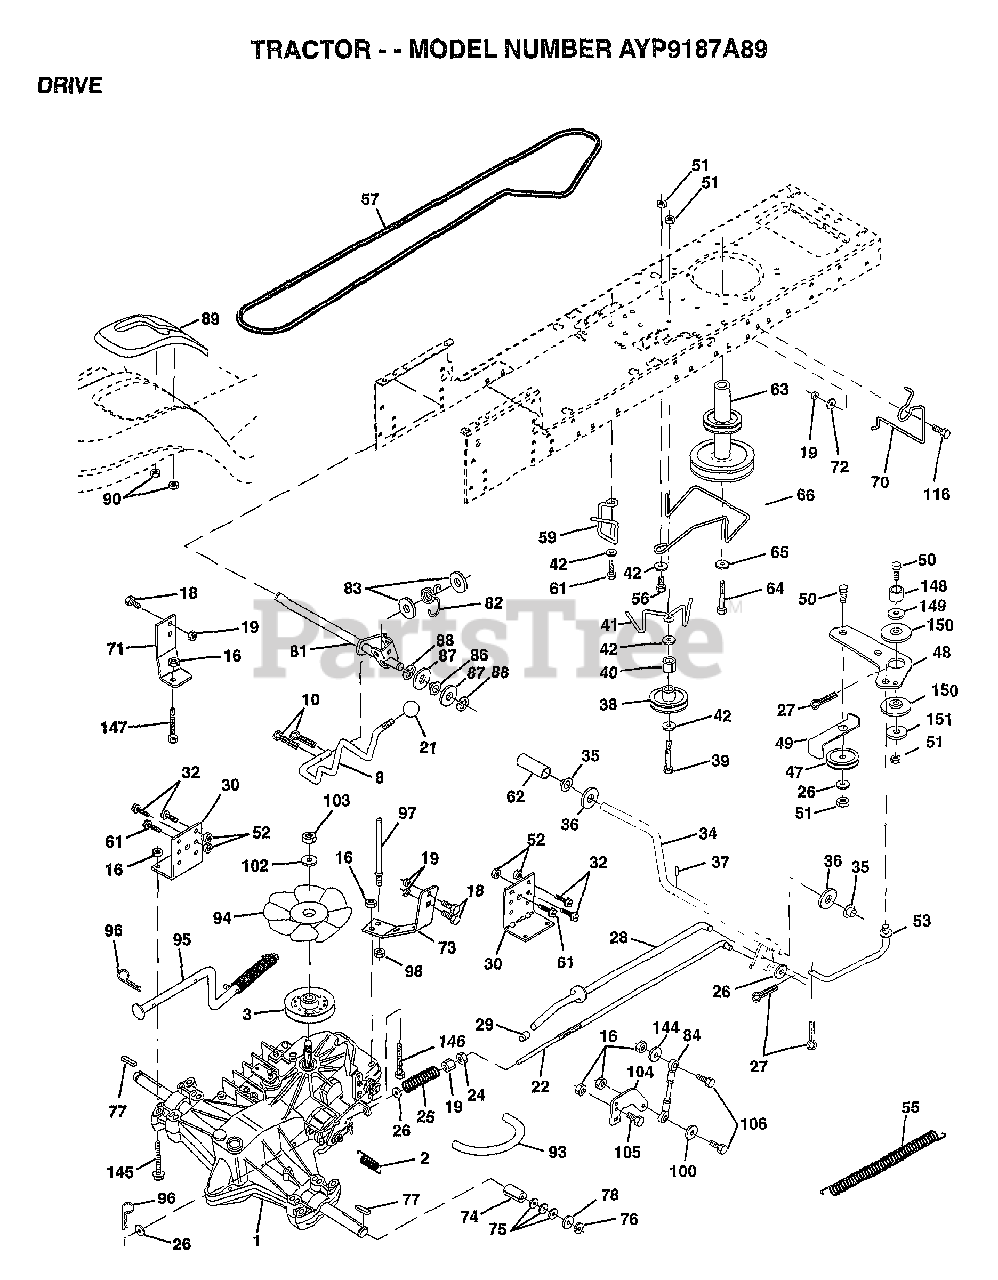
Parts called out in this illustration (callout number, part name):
1	TRANSAXLE.3100650
2	SPRING RET BRAKE
3	PULLEY.TRANSAXLE
8	"ROD SHIFT,FENDER"
10	PIN COTTER 1/8
16	NUT
18	BOLT
19	NUT
21	KNOB T (1/2-HOLE)
22	ROD.BRAKE.HYDRO.
24	NUT
25	SPRING ROD LT
26	WASHER
27	COTTER PIN
28	ROD.BRAKE.PARK.LT
30	TRANSAXLE MTG BKT
32	BOLT
34	SHAFT ASM-PEDAL F
35	NYLON BEARING
36	WASHER LT
38	PULLEY.IDLER.FLAT
39	BOLT
40	SPACER T
42	WASHER
48	BELLCRANK.CLUTCH
49	RETAIN BELT
53	"LINK, CLUTCH T"
55	"SPRING, RETURN LT"
57	V-BELT.GROUND.HYD
59	KEEPER BELT CNTSP
61	SCREW
62	PEDAL COVER T
63	PULLEY.ENGINE
64	BOLT
65	LOCKWASHER
66	ENGINE BELT KEEPR
70	KEEPER BELT ENG
71	STRAP TORQ LH HYD
72	WASHER
73	"STRAP-TORQUE,RH"
74	SPACER SPLIT
75	WASHER
76	E-RING LT
77	SQUARE KEY
78	WASHER
81	SHAFT.ASM.CROSS
82	"SPRING,TORSION"
83	WASHER
84	ROD.TIE
86	BUSHING
87	WASHER D
88	KLIP RING
90	NUT
93	"LINE FUEL HYD 4"""
94	"FAN 7"" HYDRO"
97	BOLT KEEPER RH
98	NUT
100	WASHER M
102	WASHER BELLEVILLE
104	ARM CONTROL HYDRO
105	SCREW CAP 5/16-18
106	BOLT
116	BOLT RDHD 3/8-16
144	WASHER
145	BOLT.HEX.FLGHD
146	BOLT.HEX.FLGHD.
147	BOLT.HEX.FLGHD
149	SPACER RETAINER
150	BUSHING.NYLON
151	WASHER
